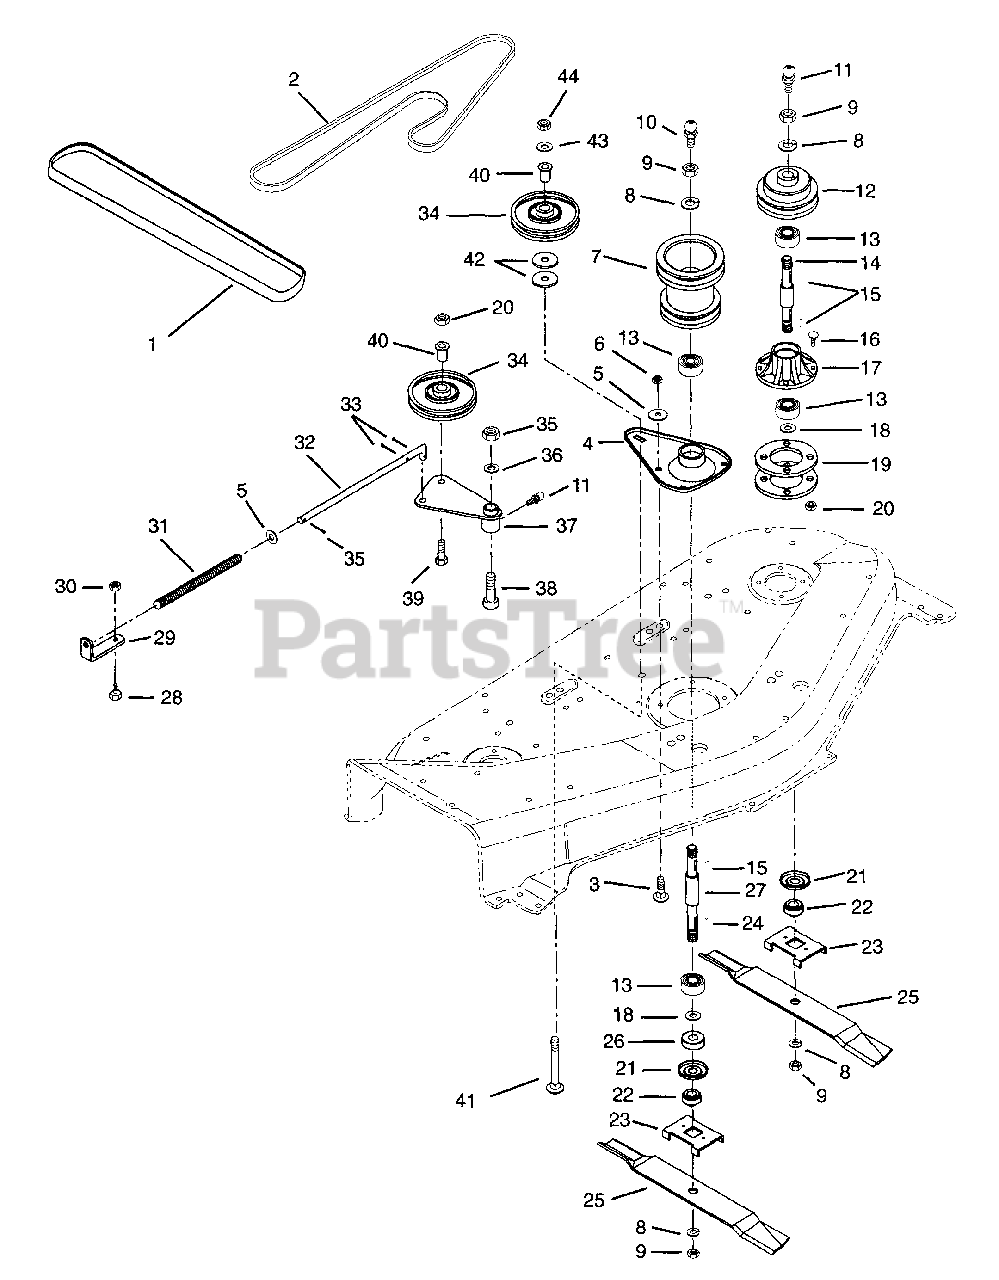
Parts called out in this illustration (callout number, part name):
1	BELT,HA 51.20 WRAPPED C-L2089
1	V-BELT, HA-WRAPPED
2	V-BELT, HA-WRAPPED
3	BLT-RDHDSQNK .38-16X.62 GR5 PL
4	HOUSING,SPINDLE
5	WSHR-FL-STL.406X.812X.065PL
6	NUT-LK-CTR .375-16 GR A PL
7	SHEAVE, 48" DECK
8	WSHR-LK .750X.188 MED PL
9	NUT-JAM .75-10 PL
10	FTG,LUBE 1/8
11	FTG-LUBE .25-28X.256 YWZC
13	BRG-BALL .750X1.781X.61
14	SPINDLE SHAFT W/ZERK
15	KEY-WDRF .188X.625X.25 SAE 61
16	BLT-RDHDSQNK .375-16X.75 PL
17	SPINDLE HOUSING
18	WSHR-FL-STL .754X1.000X.032
19	SPACER, SPINDLE
20	NUT-LK-JAM-CTR .375-16 PL
21	BEARING SLINGER
22	RETAINER HUB
23	BLADE TRAY 48
24	KEY-SQ .188X.625X.188 SAE 61
25	BLADE
26	WSHR-FL-STL .755X1.250X.125
27	SPINDLE SHAFT W/ZERK & KEY
28	BLT-HEX .31-18X.50 GR5
29	BRACKET
30	NUT-LK .312-18 GR A PL
31	SG-COMP .106X.63X 12.0 WLD 62
32	ROD-IDLER SPRING
33	PIN-COTR .09X.75 PL
34	IDLER, PLASTIC, 4.00 X .50 ID
35	NUT-LK-CTR .50-13
36	WSHR-FL-STL .505X.880X.072 PL
37	IDLER ARM W/ZERK
38	BLT-HEX .50-13X1.50 PL GR2
39	BLT-BTHD .38-16X1.25 GR5
40	SPACER -FLANGED .390X.500X.781
41	BLT-RDHDSQNK .38-16X2.00
42	WSHR-HDND-THR .390X1.50X.125PL
43	WSHR-FL-STL .38X.875X.083 PL
44	NUT-LK-NYL .375-16 PL
